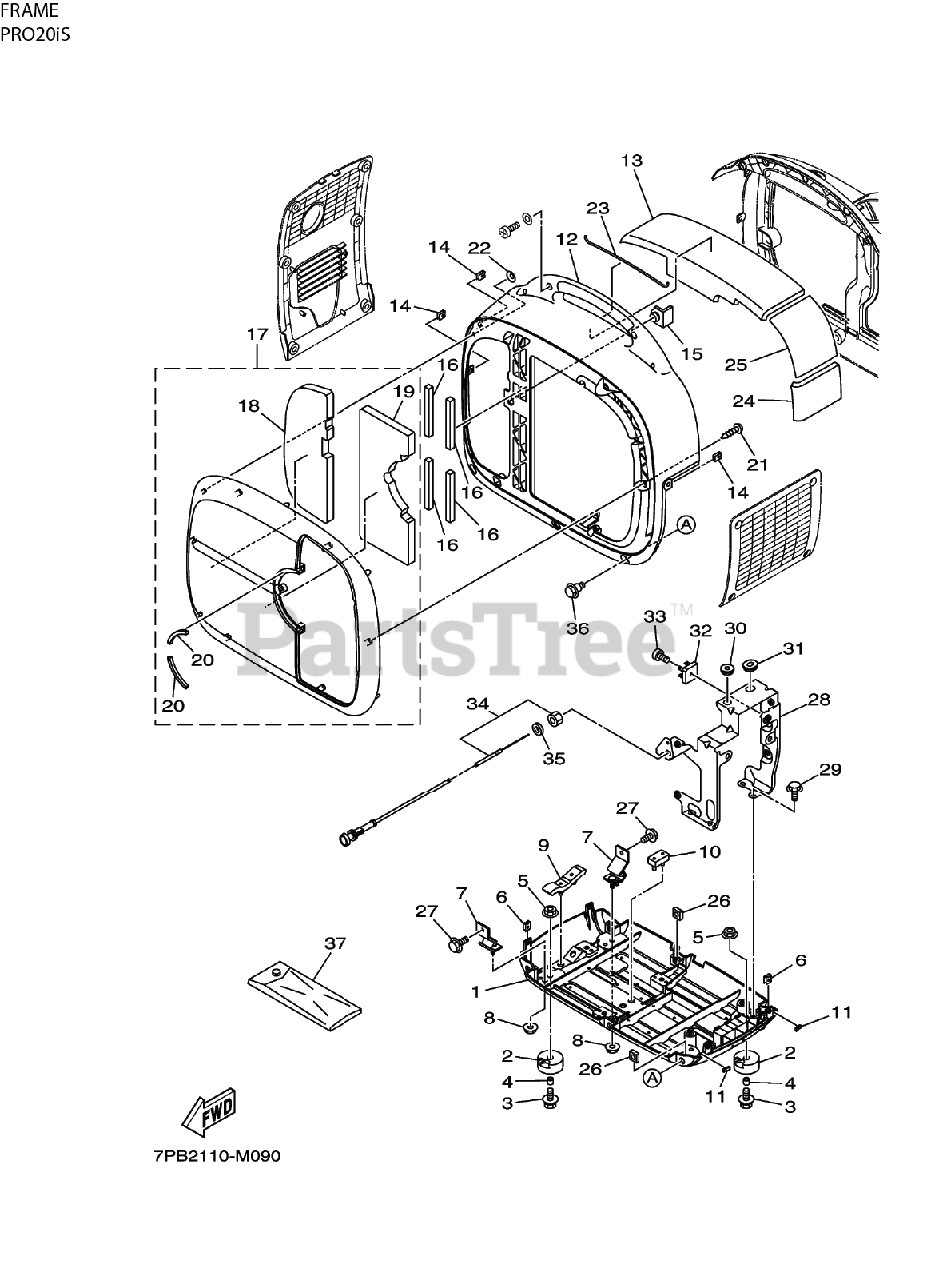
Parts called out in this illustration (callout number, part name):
1	BASE, AIR CLEANER - MOUNTING
2	MOUNT, INSULATOR
3	SCREW - BOLT W/WASHER
5	NUT, FLANGE
6	NUT, FLANGE
7	MOUNT, INSULATOR
8	NUT, FLANGE
9	DAMPER, STOPPER
10	ISOLATOR, VIBRATION DAMPER SHOCK ABSORBE
11	PLATE, DAMPER
12	COVER, AIR CLEANER - FRONT
14	NUT, FLANGE
16	DAMPER, PLATE
17	COVER, AIR CLEANER - COVER ASSY 2
20	DAMPER, PLATE
21	SCREW - TAPPING
22	NUT, SPRING
23	COVER, AIR CLEANER - COVER DUST SEAL 1
24	DAMPER, PLATE
25	DAMPER, PLATE
26	NUT, SQUARE
27	SCREW - BOLT FLANGE
28	BRACKET, FUEL TANK
29	SCREW - BOLT FLANGE
32	RECTIFIER ASSEMBLY
33	SCREW - PAN HEAD
34	CABLE ASSEMBLY, STARTER
35	WASHER, PLATE
36	SCREW - BOLT
37	KIT, TOOL
